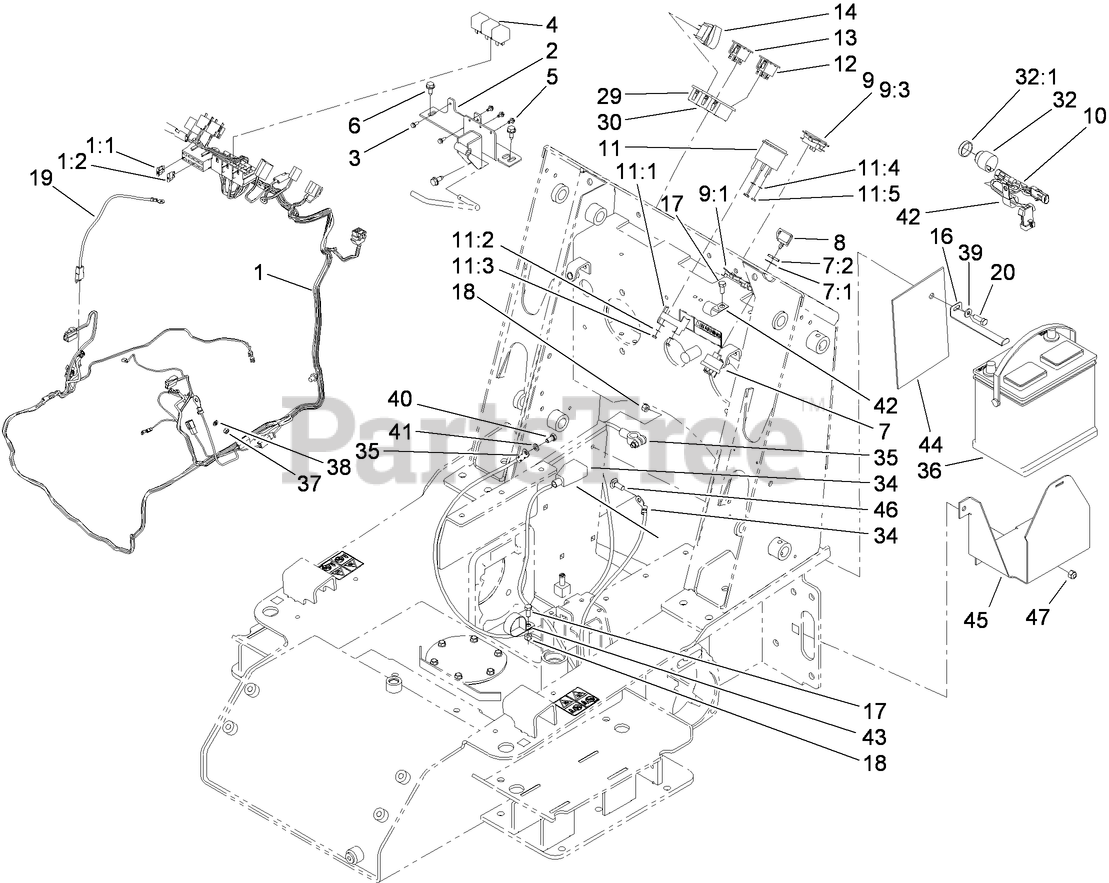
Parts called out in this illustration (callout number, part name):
1	HARNESS-WIRE
1:1	HARNESS-LINK, FUSIBLE
1:2	HARNESS-FUSIBLE LINK (14FL)
2	RELAY BRACKET ASM
3	SCREW
4	RELAY
5	SCREW-HWH
6	SCREW-HWHTF
7	Key Switch ASM
7:1	WASHER-TOOTH, INTERNAL
7:2	NUT-HH
8	KEY-IGNITION
9	METER-HOUR
9:1	CLIP-MOUNTING
9:3	HOUR METER BODY
10	HARNESS-WIRE, NEUTRAL
11	GAUGE-FUEL
11:1	BRACKET-MOUNTING, GAUGE
11:2	WASHER-LOCK, INT
11:3	NUT-HEX
11:4	WASHER-LOCK / EXT
11:5	NUT-HEX
12	LAMP-WARNING
13	LAMP-WARNING
14	SWITCH-ROCKER
16	CLAMP-BATTERY
17	SCREW-HH
18	NUT-LOCK, NI
19	HARNESS-WIRE
20	SCREW-HH
29	BRACKET-END
30	BRACKET-MIDDLE
32	AUDIO ALARM ASM
32:1	NUT-PLASTIC, KNURLED
34	CABLE-BATTERY, POSITIVE
35	CABLE-BATTERY, NEGATIVE
36	BATTERY
37	NUT-HEX
38	WASHER-LOCK, SPRING
39	WASHER-FLAT
40	SCREW-HH
41	WASHER-LOCK
42	CLAMP-J
43	CLAMP-R
44	GUARD-BATTERY
45	MOUNT-BATTERY
46	BOLT-CARR
47	NUT-LOCK, NI
